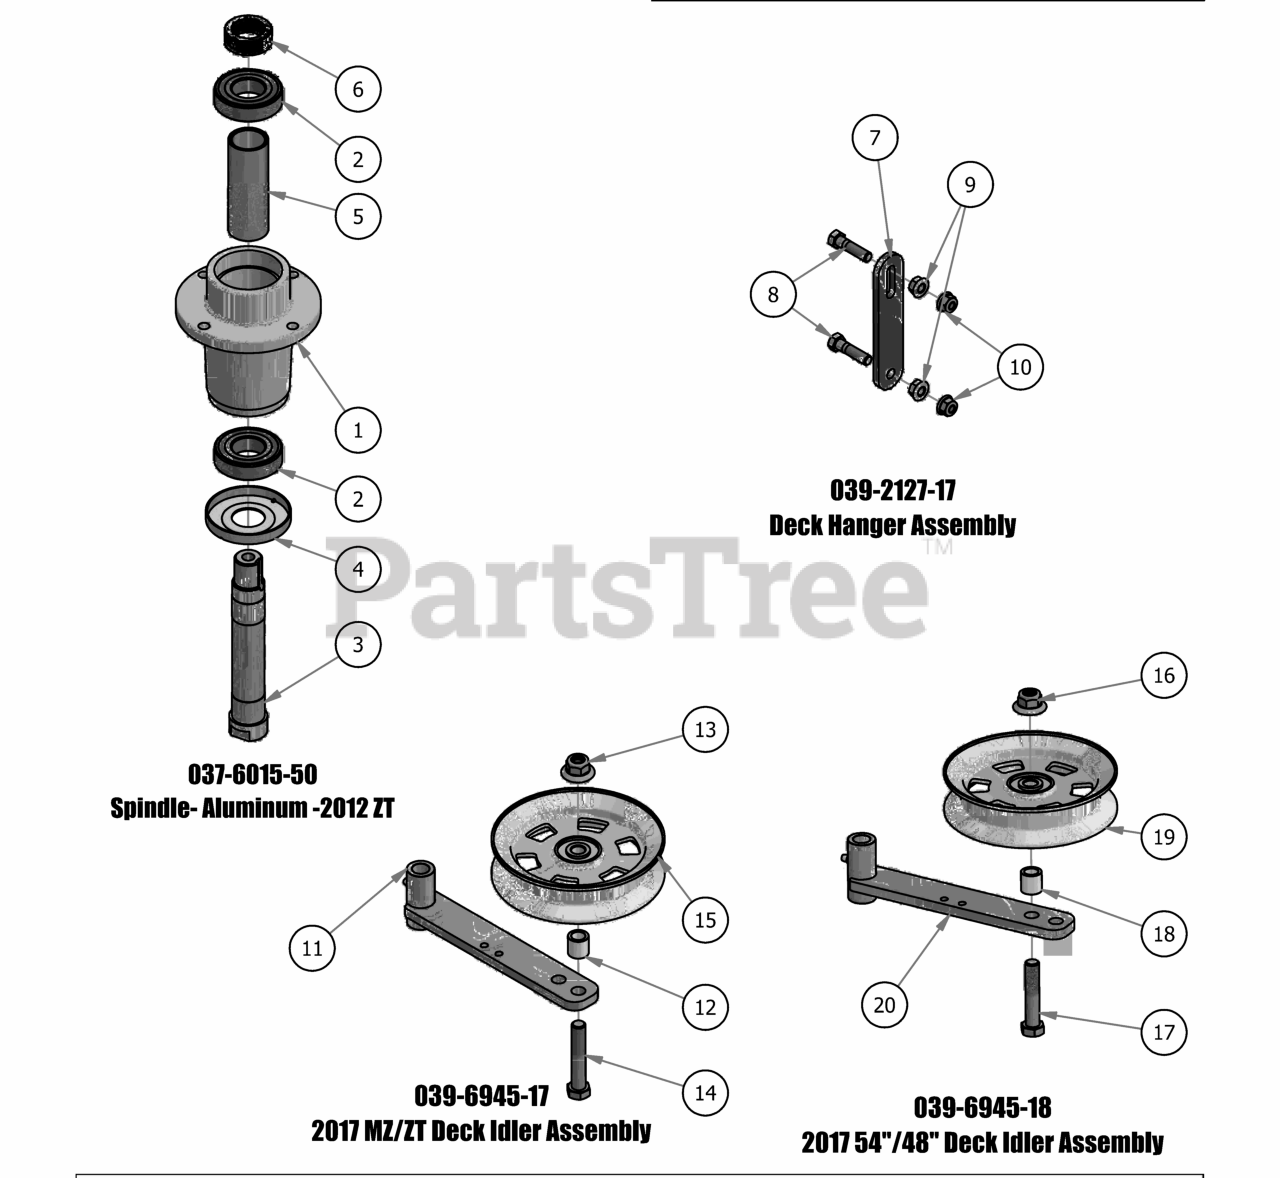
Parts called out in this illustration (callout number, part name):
1	Aluminum Spindle Housing -2010
2	Spindle Bearing, 2004 and up
3	Short Spindle Shaft w/Locking
4	Dust Cover
5	Tube Spacer for Spindle Shaft
6	Collar Spacer - Top of Spindle
7	2017 MZ/ZT Deck Hanger
8	3/8" x 1 1/2" Hex Bolt
9	3/8" Flange Nut
10	3/8" Nylock Flange Nut
11	Deck Idler
12	Spacer 3/4 OD x 1/2 ID x 3\4 Length
13	1/2-13 Nylon Flange Nut
14	1/2" x 2 3/4" Hex Bolt
15	5" Idler Pully
16	1/2-13 Nylon Flange Nut
17	1/2" x 2 1/2" Hex Bolt
18	Spacer 3/4 OD x 1/2 ID x 3\4 Length
19	5" Idler Pully
20	Deck Idler
